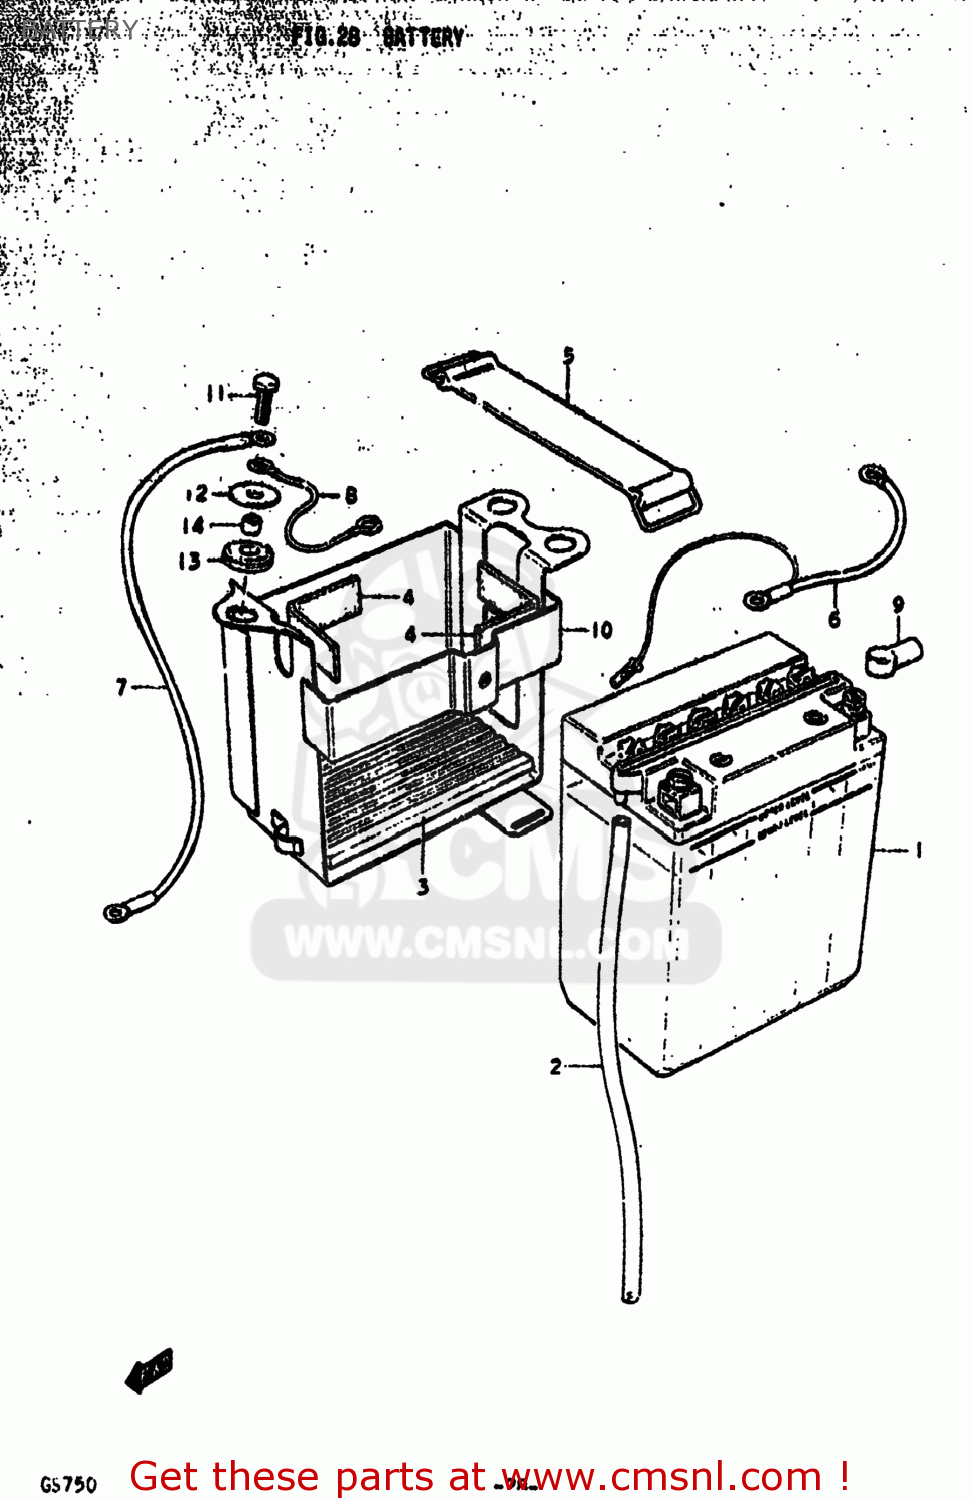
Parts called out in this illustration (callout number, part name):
1	BATTERY ASSEMBLY
2	HOSE,BATTERY EXHAUST
3	PROTECTOR,BATTERY
4	PROTECTOR,20X9
5	BAND
6	WIRE,BATTERY PLUS
7	WIRE,STARTER MOTOR LEAD
8	WIRE
9	CAP,TERMINAL
10	HOLDER,BATTERY
11	BOLT, UPPER
12	WASHER(6,5X22X1.6)
13	CUSHION
14	SPACER(6.2X8.3X5.7)
